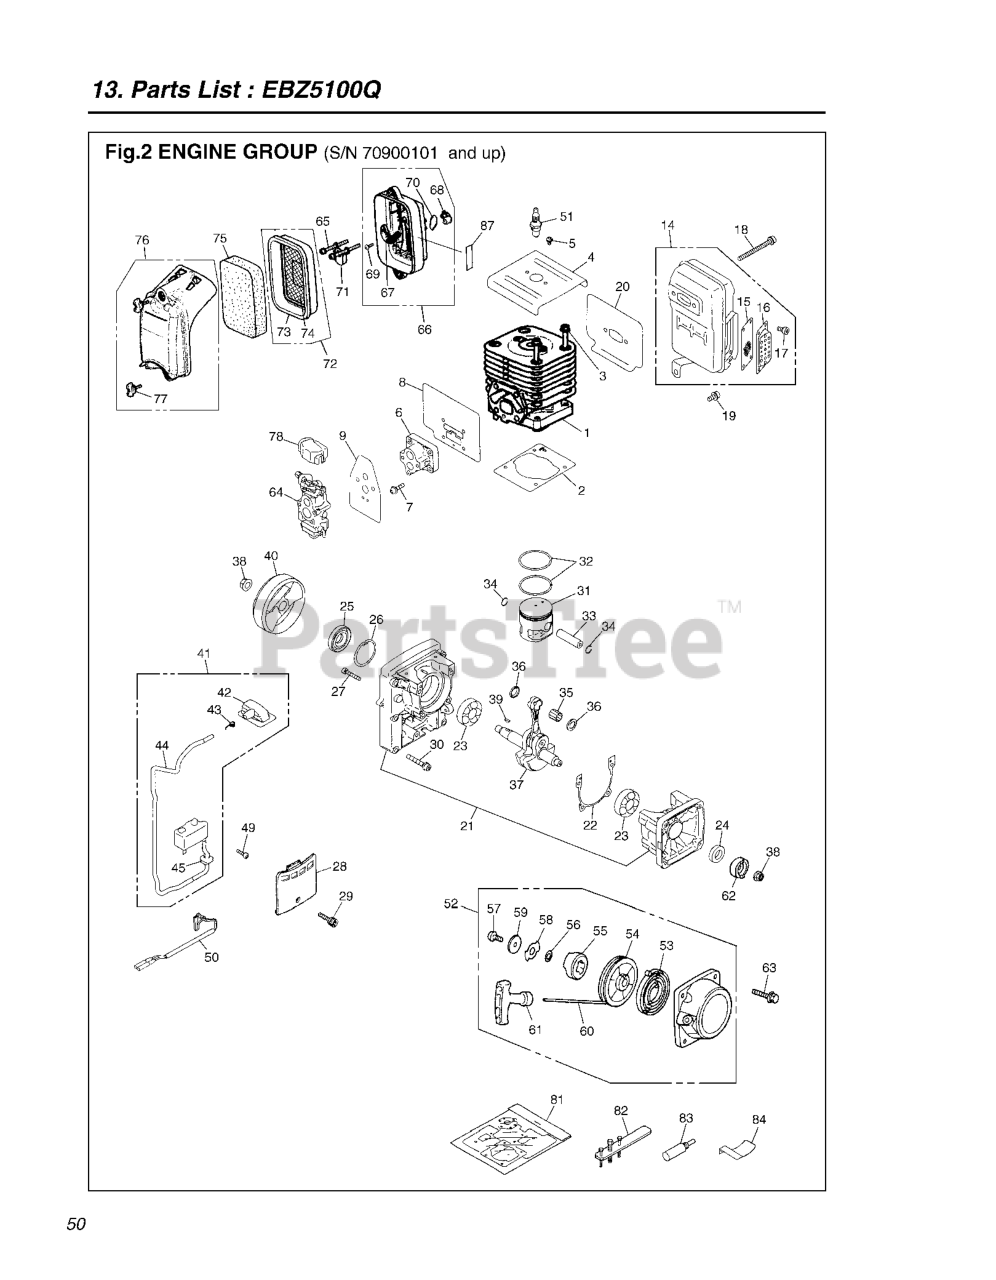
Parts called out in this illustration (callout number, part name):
1	CYLINDER
2	GASKET, BASE
3	BOLT
4	CYLINDER COVER
6	INSULATION
8	GASKET,INSULATOR
9	GASKET, CARB
14	MUFFLER ASSY
15	SPARK ARRESTOR SCREEN
16	EXHAUST DUCT
20	GASKET
21	CRANKCASE
26	SNAP RING
30	BOLT
32	PISTON RING
33	PISTON PIN
34	SNAP RING
37	CRANKSHAFT
39	KEY
41	COIL-A
43	SPRING
44	RP TUBE-A
45	GROMMET
50	CORD-COMP
51	PLUG CMR7H
52	STARTER ASSY
54	STARTER PULLEY
55	STARTER PAWL
58	RETAINER
59	WASHER
60	CHORD
62	PULLEY
64	CARBURETOR ASSEMBLY
66	CARBURETOR BODY
67	PLATE
69	SCREW
72	GASKET
74	SCREEN
75	AIR FILTER
76	COVER-A
82	PULLER ASSY
87	LABEL,CHOKE
